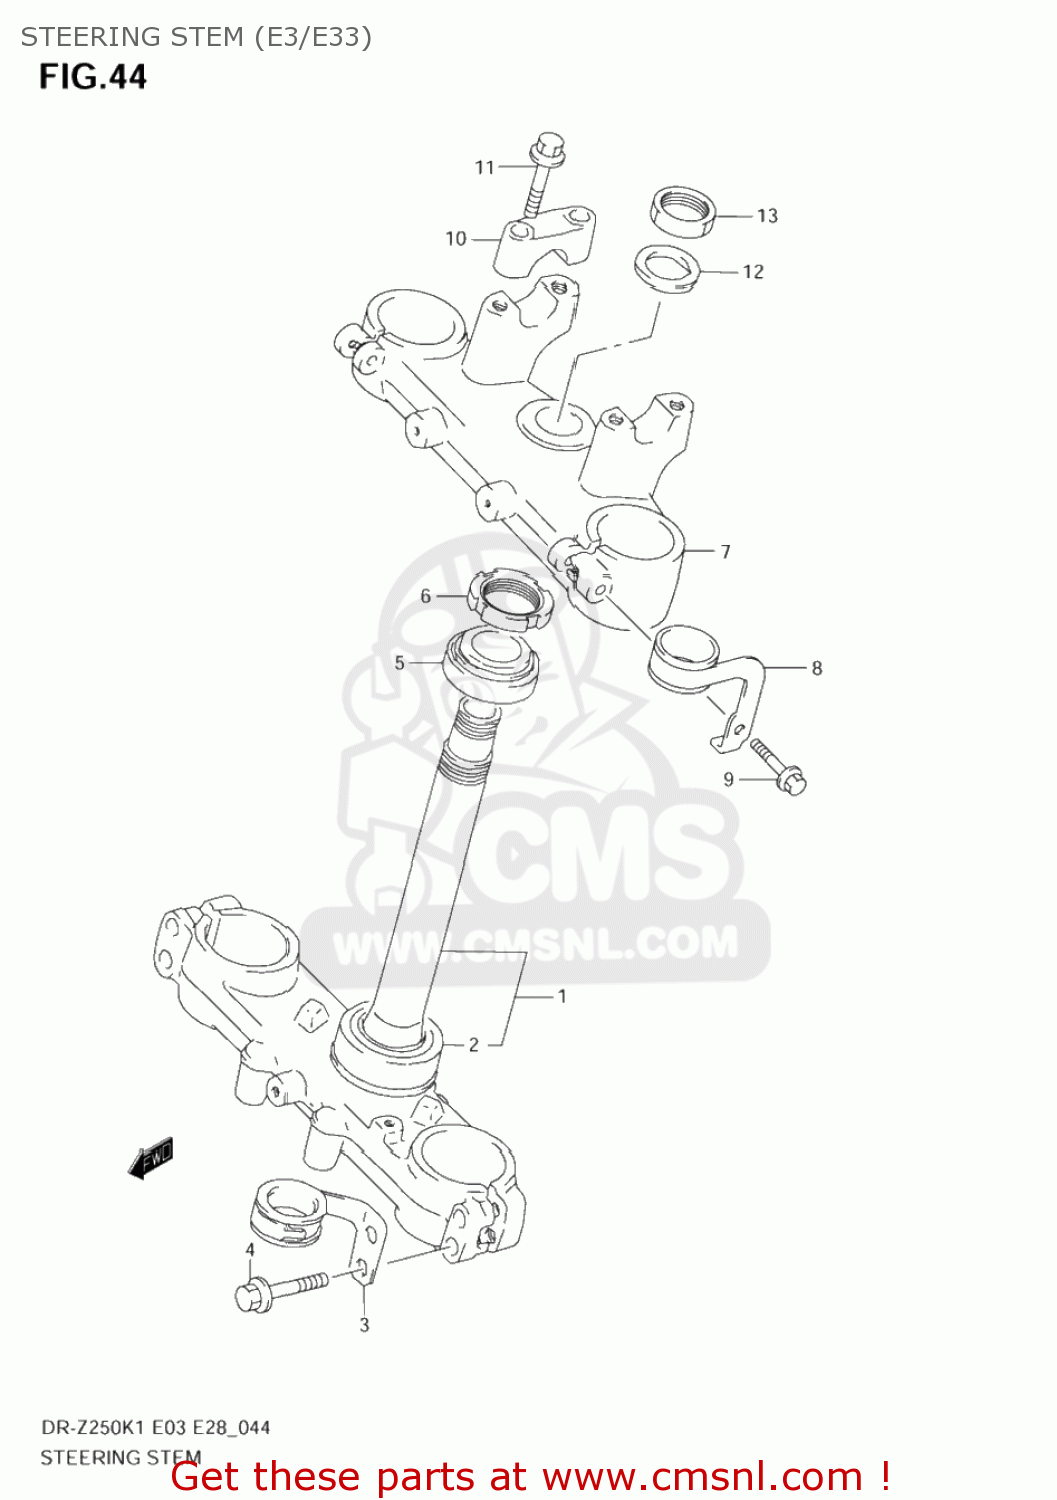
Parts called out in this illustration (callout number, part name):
1	STEM,STEERING
2	BEARING(30X52X16)
3	GUIDE,CABLE LWR,L
4	BOLT
5	BEARING(30X52X16)
6	NUT,STEERING
7	HEAD,STEERING STEM
8	GUIDE,CABLE UPR,L
9	BOLT
10	HOLDER,HANDLE
11	BOLT,HANDLE HOLDER
12	WASHER,STEM HEAD
13	NUT,STEM HEAD
